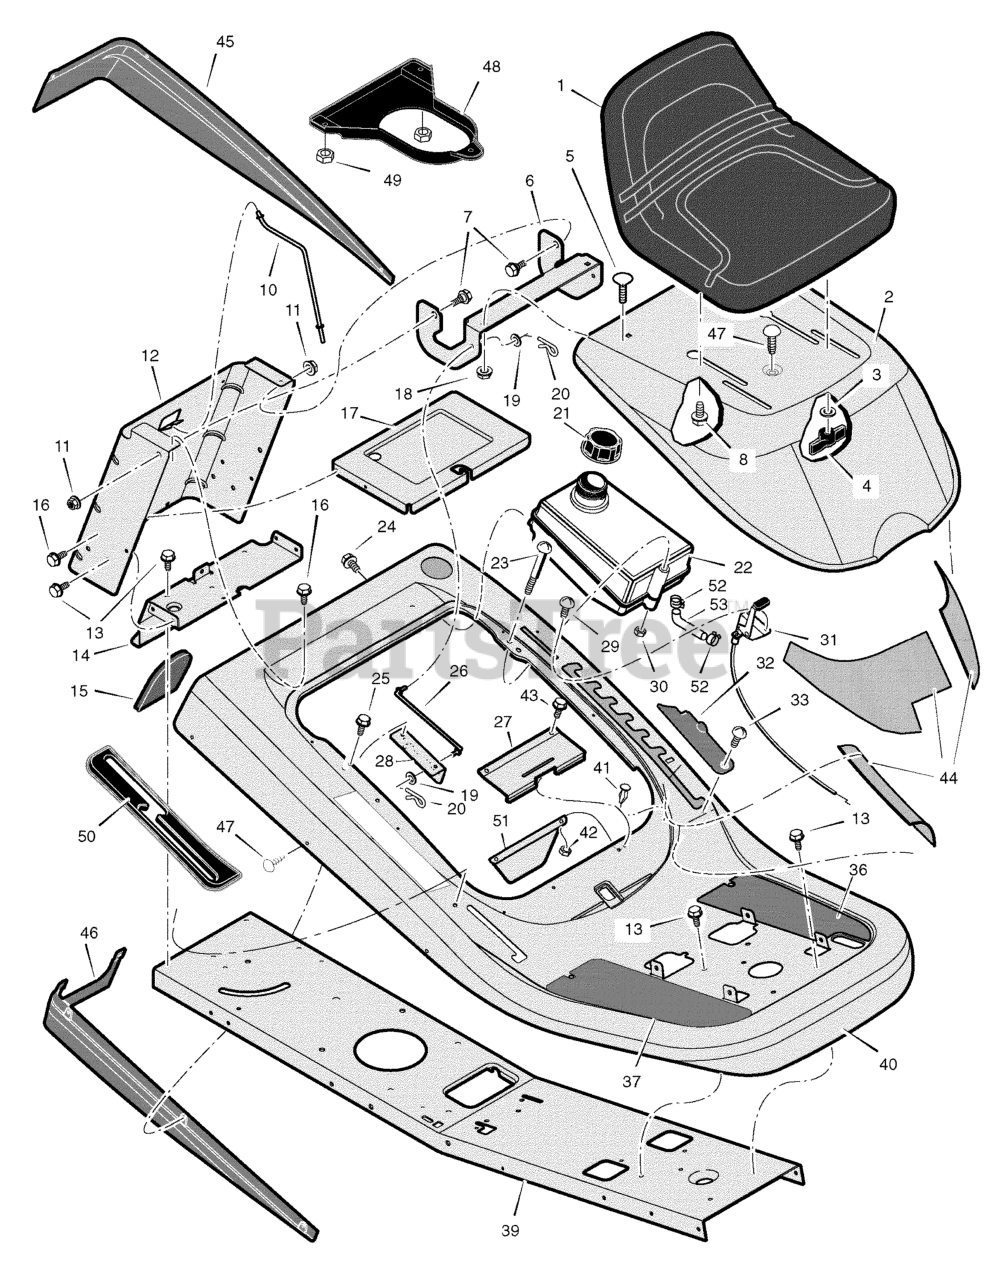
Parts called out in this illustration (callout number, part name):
3	Washer
4	Bolt, Wing
5	Bolt, Carriage
6	Bracket, Hinge
7	Bolt, Shoulder
8	Bolt, Shoulder
10	Rod, Battery
11	Nut, Flange
12	Plate, Rear
13	Screw
14	Plate, Hitch
16	Screw
17	TRAY, Battery
18	Nut, Flange
19	Washer
20	Pin, Hair
21	Cap, Fuel Tank
22	Tank, Fuel
25	Screw
26	Rod, Hood Prop
27	Spring, Seat Deck
28	Bracket, Prop Rod
29	Screw
30	Nut, NY-Lock
31	Control, Throttle
32	Cover, Detent (Black)
33	Bolt, Shoulder
36	Footmat, Left (Black)
37	Footmat, Right (Black)
40	Deck, Seat
41	Bumper
42	Nut
43	Screw
44	Kit, Foil Heat Shield
45	Trim, Left
46	Trim, Right
47	Fastener, Panel
49	NUT, HEX 5/16-18
50	Cover, Long Black
51	Shield, Heat
52	Clamp, Hose
53	Line, Fuel
